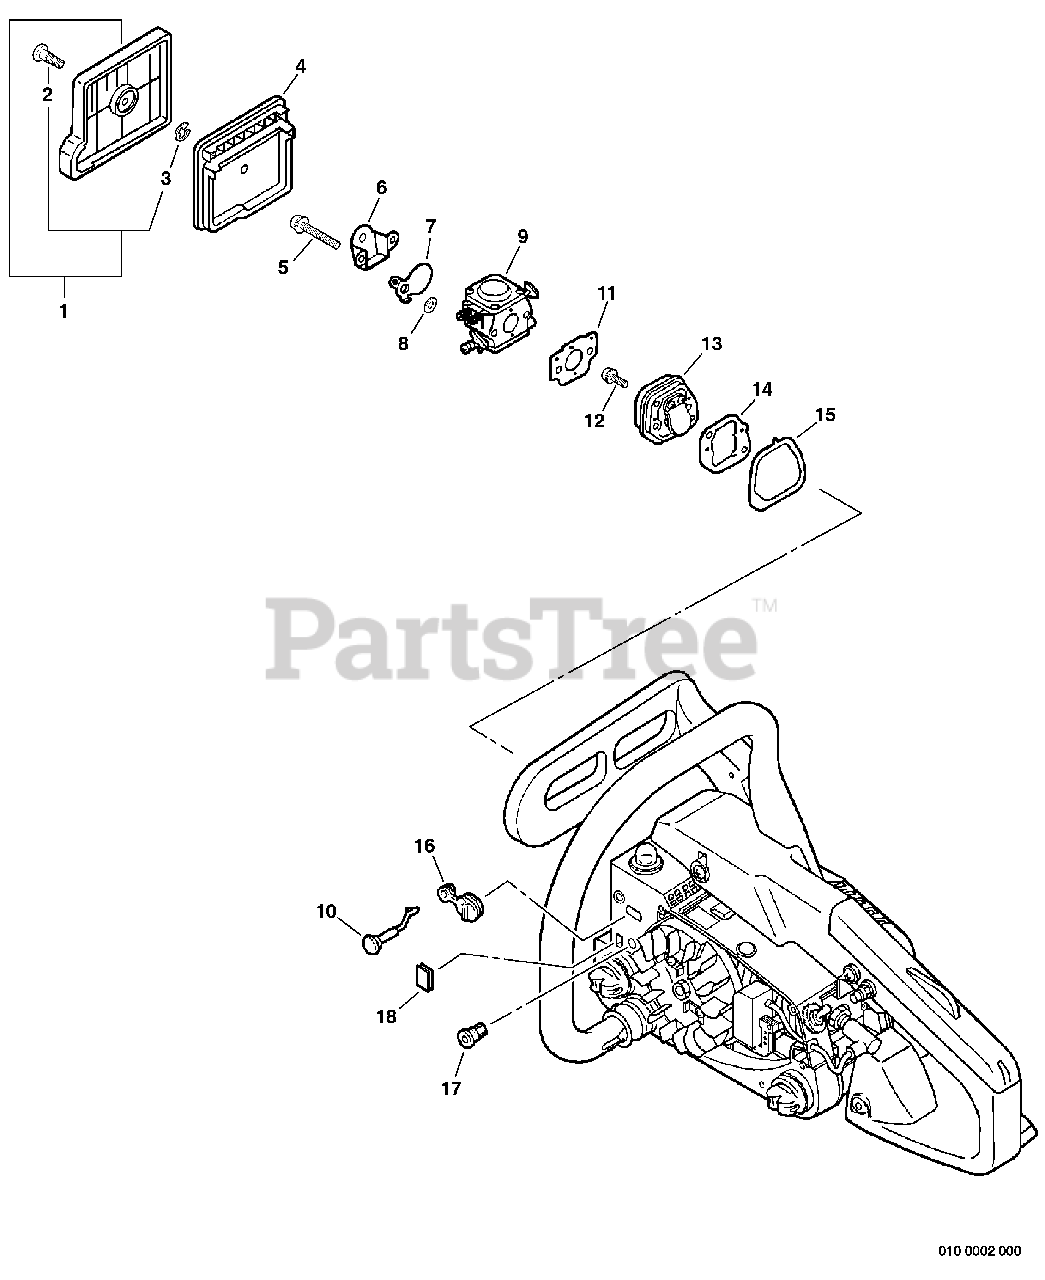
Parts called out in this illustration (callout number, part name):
1	COVER ASSY, AIR FILTER
2	THUMBSCREW
3	E-RING 4
4	FILTER, AIR
5	SCREW 5×45
6	PLATE, PREVENT
7	SHUTTER, CHOKE
8	WASHER 5.5×8×0.8
9	CARBURETOR - WT-589A
10	ROD, CHOKE
11	GASKET, INTAKE
12	SCREW 5×18
13	INSULATOR KIT
14	GASKET, INTAKE
15	SEAL, INTAKE
16	GROMMET, CHOKE
17	GROMMET, IDLE
